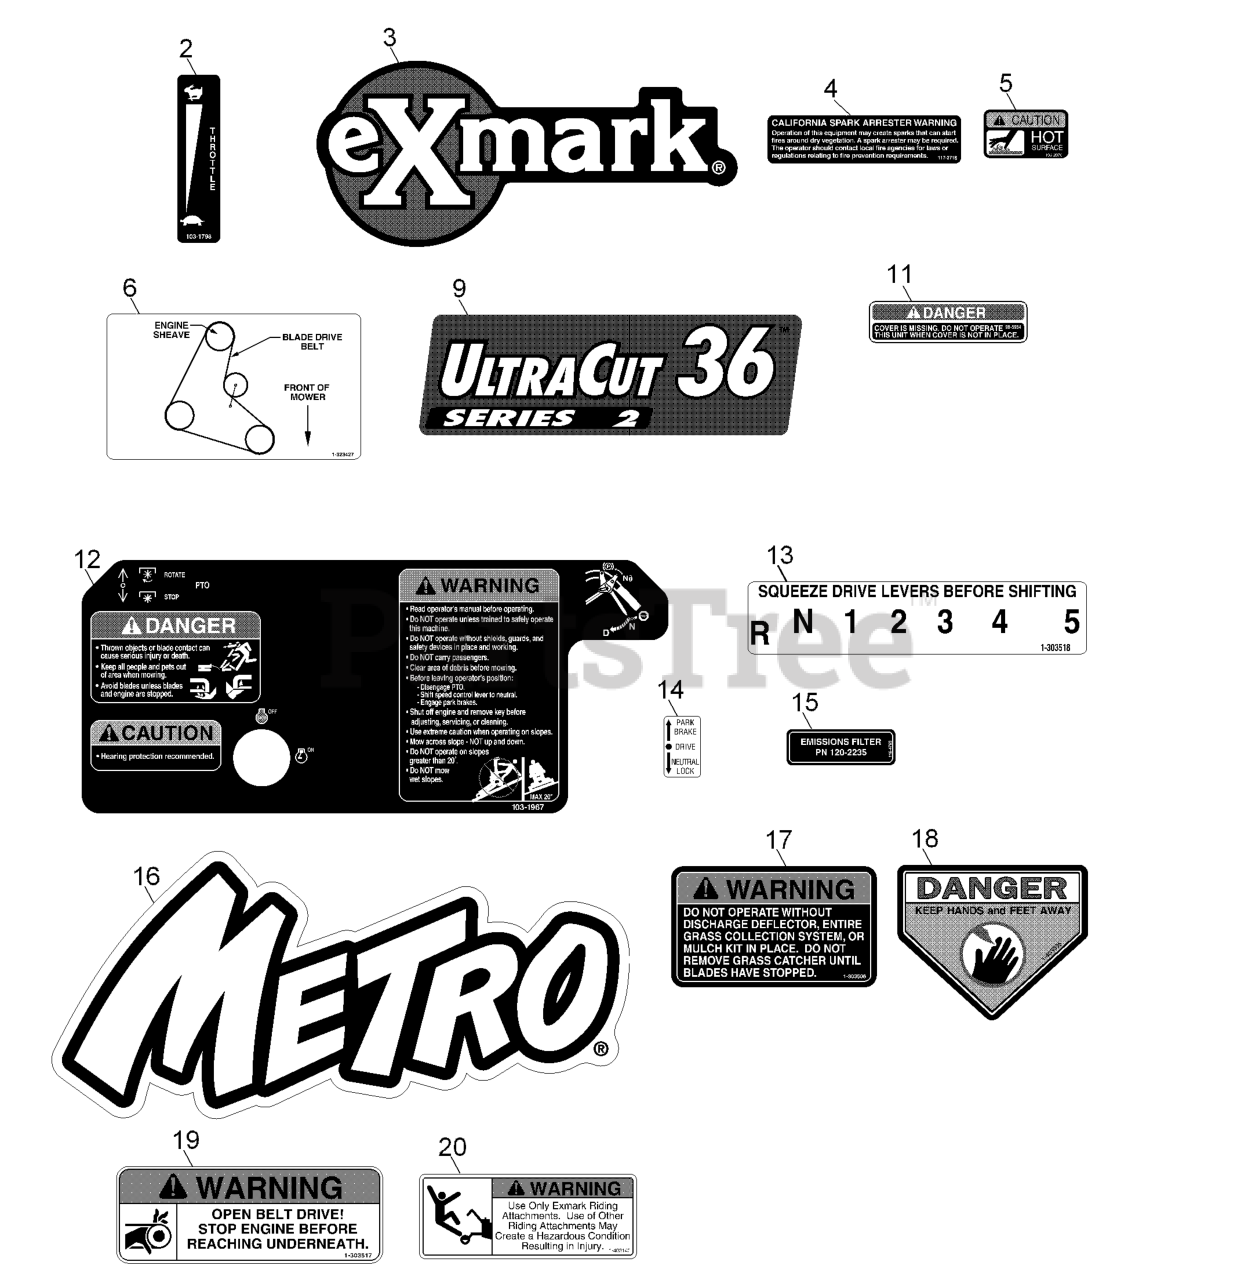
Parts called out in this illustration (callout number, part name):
2	DECAL,THROTTLE ONLY
3	DECAL,EXMARK LOGO
4	DECAL-ARRESTER, SPARK
5	DECAL-CAUTION
6	DECAL,BELT ROUTING 32/36
9	DECAL-ULTRACUT 36 SERIES
11	DECAL-COVER, MISSING
12	DECAL,CONSOLE
13	DECAL,SHIFTER
14	DECAL,NEUTRAL/BRAKE
15	DECAL-FILTER, EMISSIONS
16	DECAL,METRO MODEL
17	DECAL-WARNING, DISCHARGE
18	DECAL-DANGER
19	DECAL,BELT DRIVE
20	DECAL,SULKY WARNING
